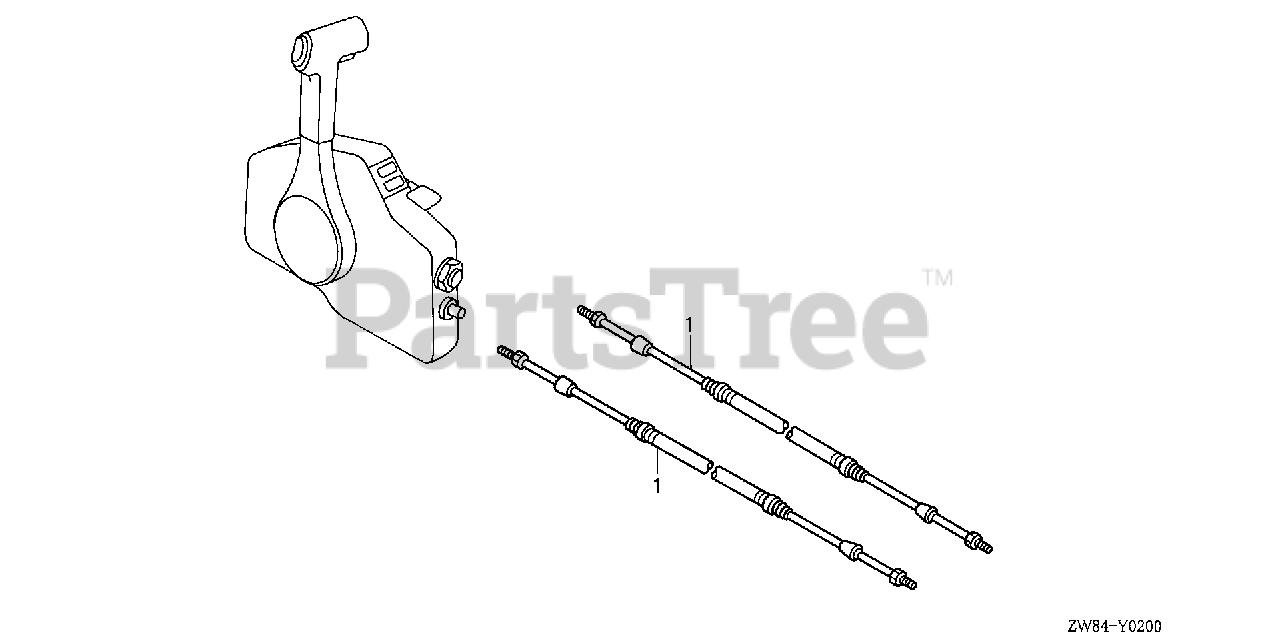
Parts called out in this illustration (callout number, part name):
1	CABLE ASSY., PUSH-PULL
1	CABLE, REMOTE CONTROL (10')
1	CABLE, REMOTE CONTROL (11')
1	CABLE, REMOTE CONTROL (12')
1	CABLE, REMOTE CONTROL (13')
1	CABLE, REMOTE CONTROL (14')
1	CABLE, REMOTE CONTROL (15')
1	CABLE, REMOTE CONTROL (16')
1	CABLE, REMOTE CONTROL (17')
1	CABLE, REMOTE CONTROL (18')
1	CABLE, REMOTE CONTROL (19')
1	CABLE, REMOTE CONTROL (20')
1	CABLE, REMOTE CONTROL (21')
1	CABLE, REMOTE CONTROL (22')
1	CABLE, REMOTE CONTROL (23')
1	CABLE, REMOTE CONTROL (24')
1	CABLE, REMOTE CONTROL (25')
1	CABLE, REMOTE CONTROL (26')
1	CABLE, REMOTE CONTROL (27')
1	CABLE, REMOTE CONTROL (28')
1	CABLE, REMOTE CONTROL (29')
1	CABLE, REMOTE CONTROL (30')
1	CABLE, REMOTE CONTROL (31')
1	CABLE, REMOTE CONTROL (32')
1	CABLE, REMOTE CONTROL (33')
1	CABLE, REMOTE CONTROL (34')
1	CABLE, REMOTE CONTROL (35')
